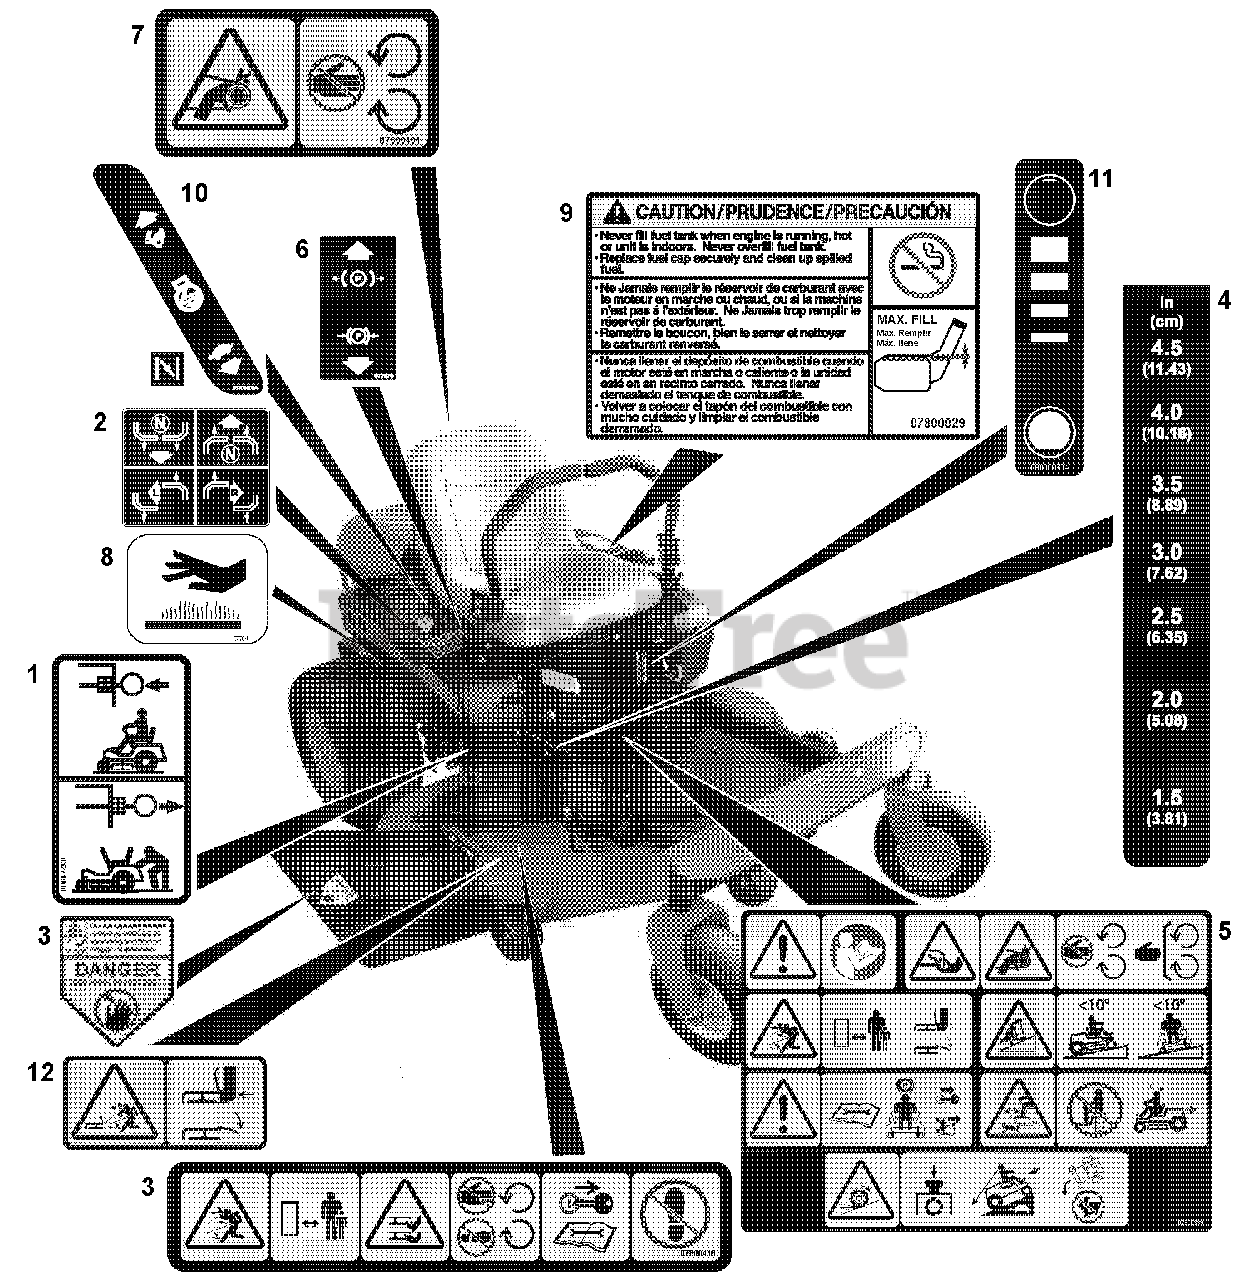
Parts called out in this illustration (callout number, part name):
1	DECAL, TRANSMISSION DISCONNECT
2	DECAL, INSTRUCTIONAL-STEERING
3	DECAL, DECK SAFETY
4	DECAL, HEIGHT OF CUT
5	DECAL, SAFETY - MAIN
6	DECAL, PARKING BRAKE LEVER
7	DECAL, SAFETY - GUARDING
8	DECAL, HOT SURFACE
9	DECAL-FUEL, WARNING
10	DECAL, SPEED CONTROL
11	DECAL, FUEL LEVEL
12	DECAL, SAFETY - DECK GUARDING
